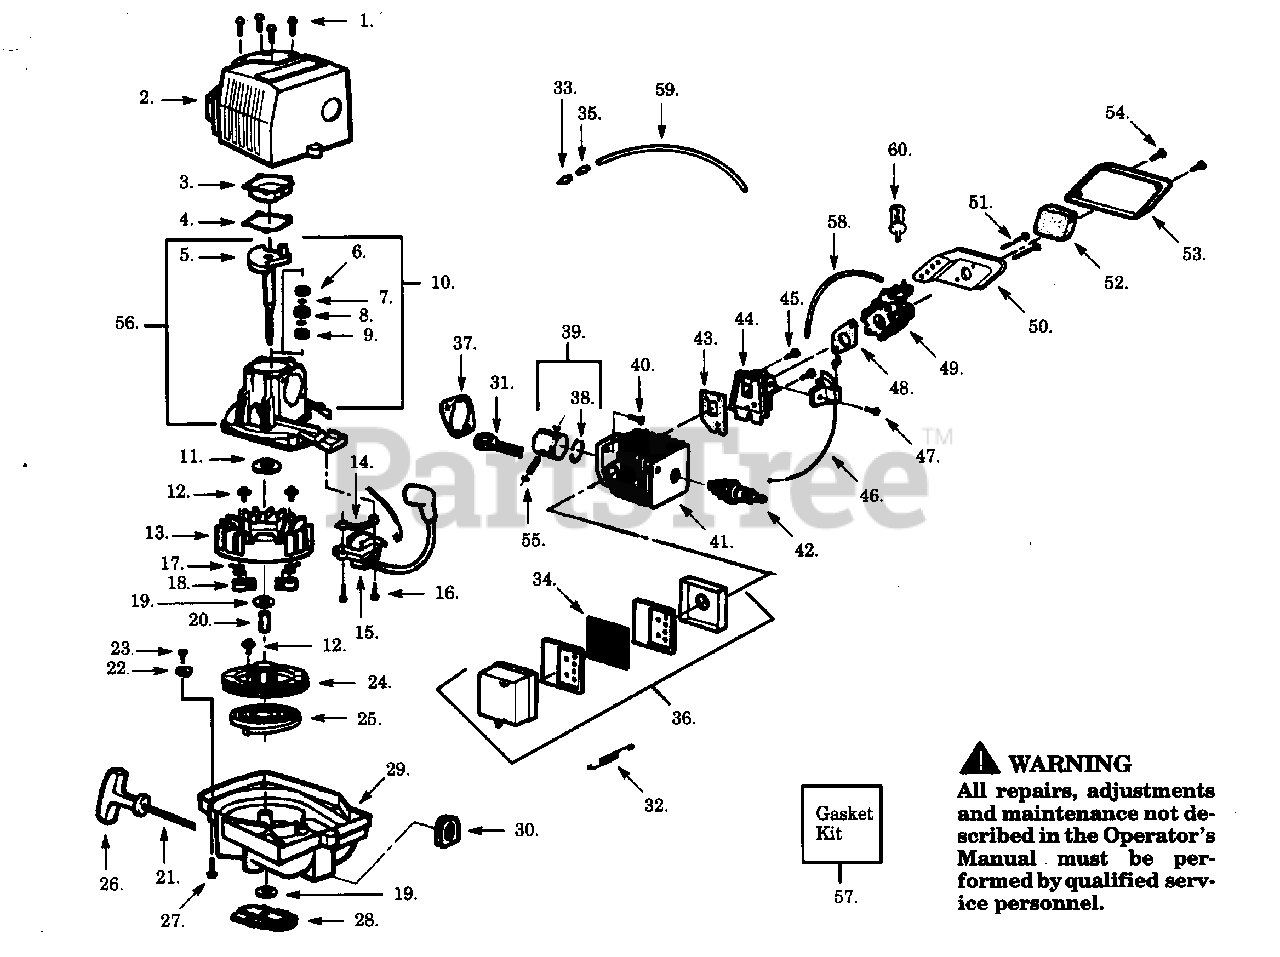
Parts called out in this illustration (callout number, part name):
3	Crankcase Cover
5	Crankshaft Ass'y.
6	Inner Bearing
7	Retaining Ring
8	Crankcase Seal
9	Outer Bearing
11	Retaining Ring
13	Flywheel Ass'y.
15	Ignition Module
17	Spring
18	Starter Dog
20	Flywheel Spacer
21	Rope Kit
22	Retainer
24	Starter Pulley Kit (Inc. 12)
25	Starter Spring
26	Starter Handle
27	Screw
28	Clutch Ass'y. Kit
29	Fan Housing
31	Connecting Rod Assy
32	Muffler Spring
33	Check Valve
34	Muffler Screen
35	Vent Fitting
36	Muffler Kit
37	Cylinder Gasket
38	Piston Ring
39	Piston Kit (Inc. 38,55)
42	Spark Plug
43	Gasket
44	Carb. Adaptor
46	Throttle Cable Ass'y.
48	Gasket
49	Carburetor WT-221
52	Air Filter Foam
53	Air Filter Cover
55	Piston Pin Retainer
58	Fuel Line
59	Vent Line
60	Fuel Pick-up Ass'y.
